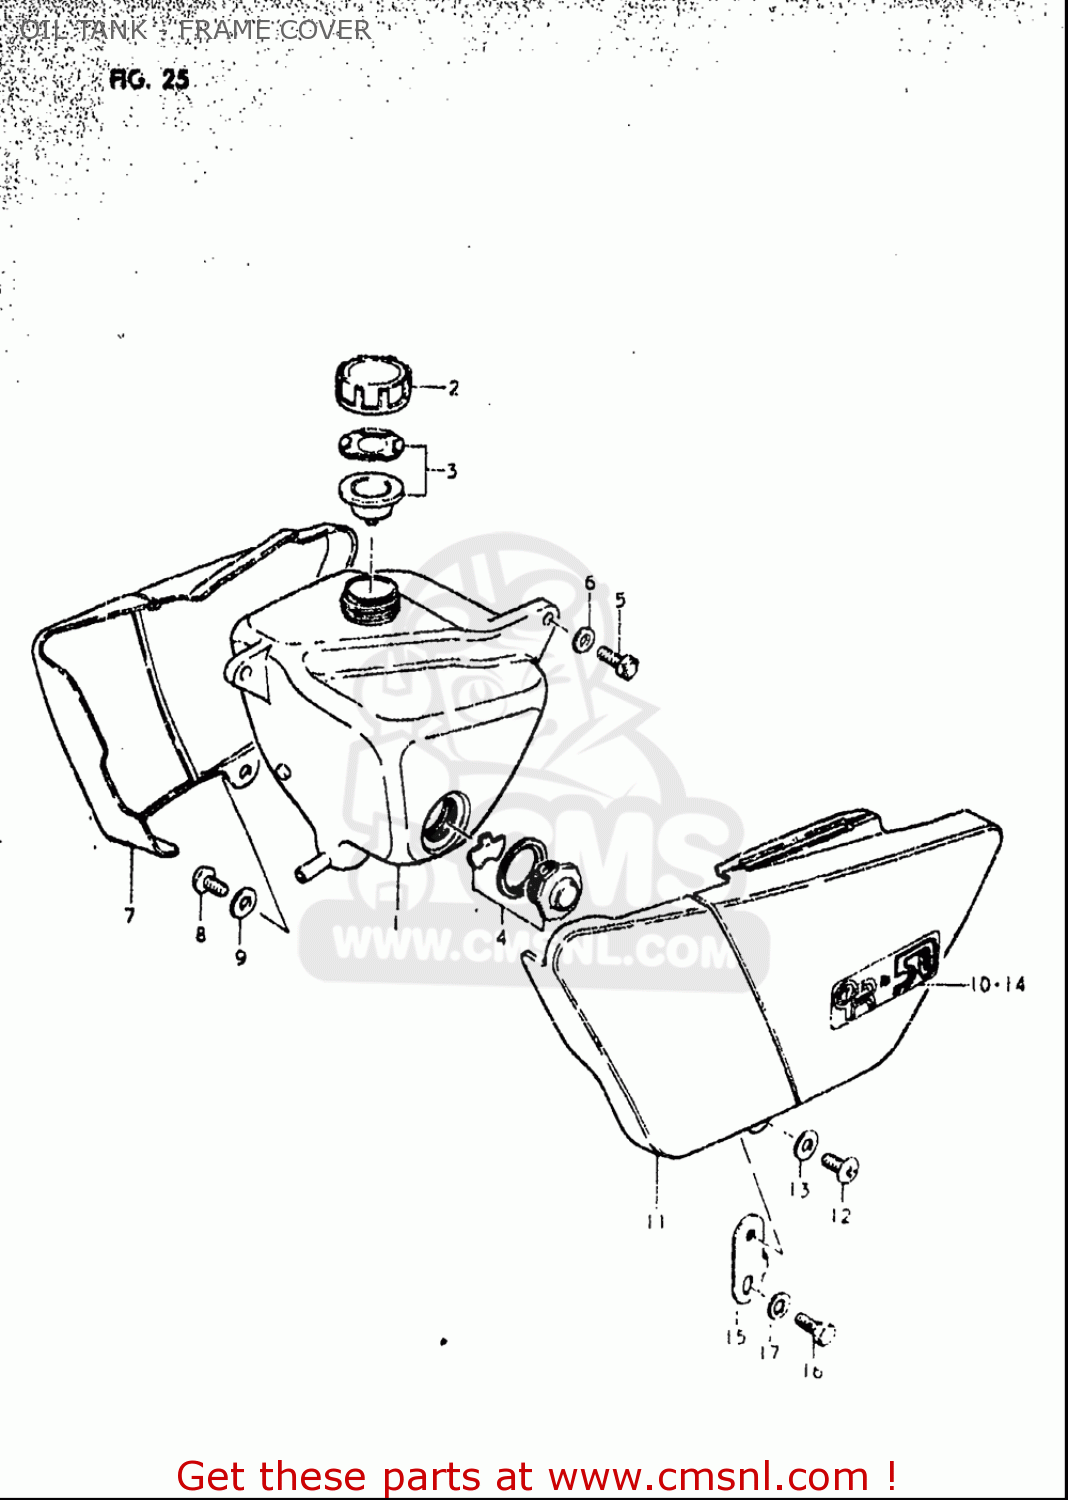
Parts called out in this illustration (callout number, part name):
2	CAP,OIL TANK
3	GASKET SET (NAS)
4	LENS SET,OIL LEVEL
5	BOLT
6	WASHER(6.5X18X1.6)
8	SCREW 6X12
9	WASHER(6.5X18X1.6)
11	COVER,FRAME,LEFT
12	SCREW 6X12
13	WASHER(6.5X18X1.6)
16	BOLT
17	WASHER
